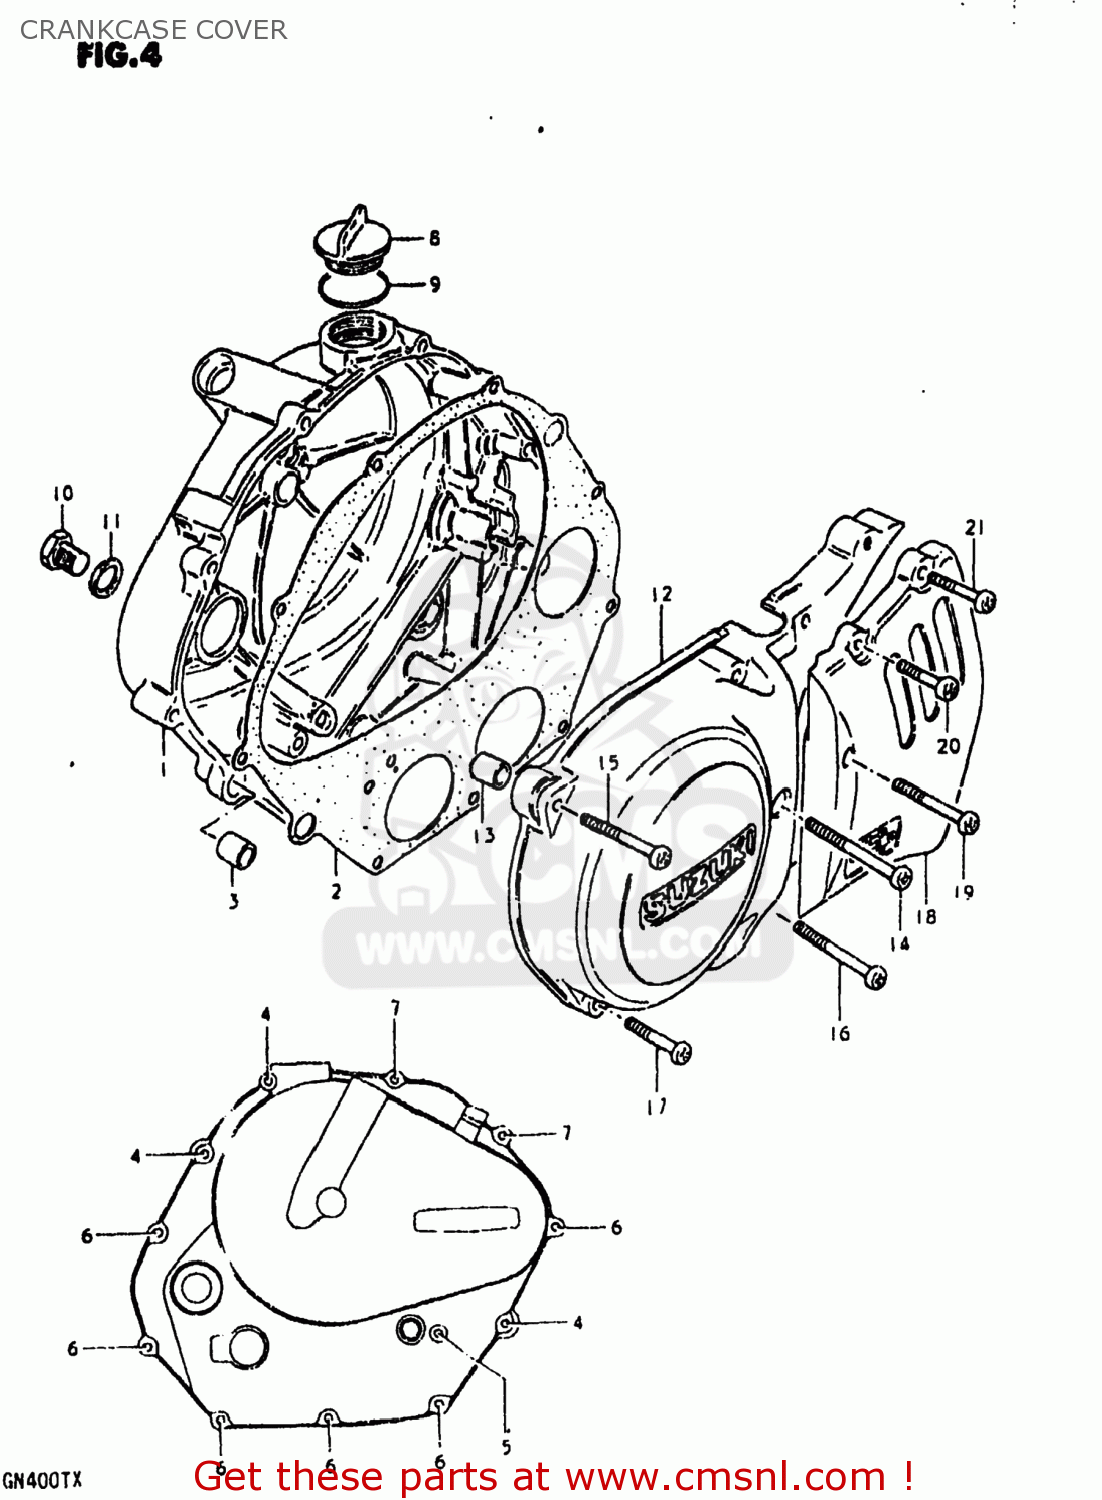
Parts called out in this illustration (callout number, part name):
1	COVER,CLUTCH
2	GASKET,CLUTCH COVER (MCA)
3	PIN
4	SCREW
5	SCREW
6	SCREW (6X35)
7	SCREW
8	CAP
9	O RING(D:2.2,ID:32)
10	PLUG (14X12)
11	GASKET(14X19.2X2) (NAS)
12	COVER
13	PIN
14	SCREW 6X60
15	SCREW
16	SCREW (6X45)
17	SCREW (6X35)
18	COVER,SPROCKET
19	SCREW
20	SCREW
21	SCREW
